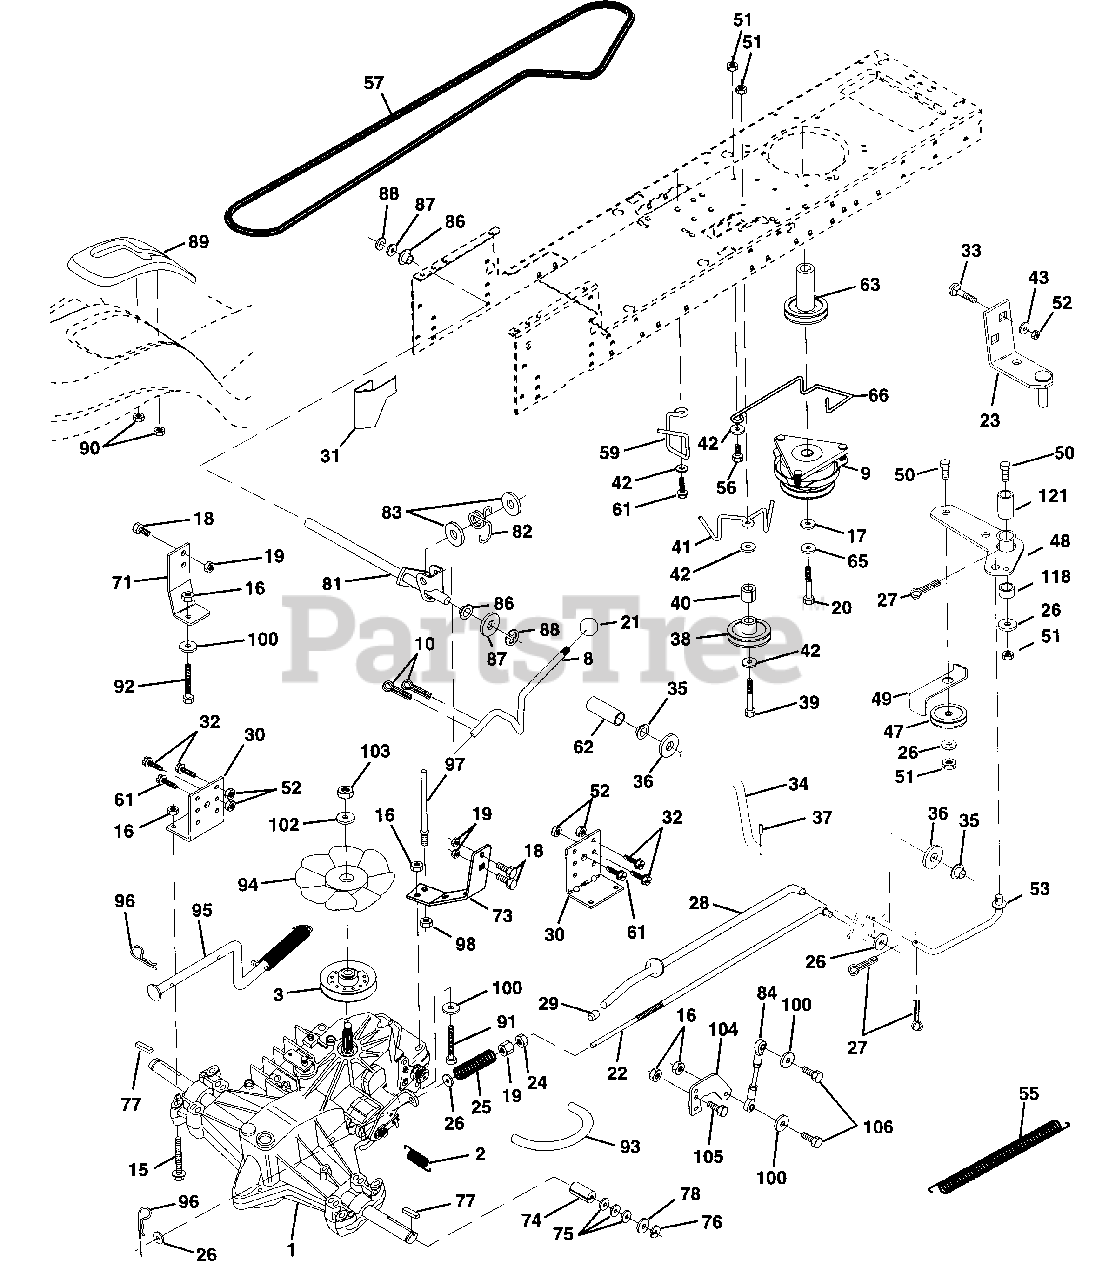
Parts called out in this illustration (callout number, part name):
1	Transaxle w/cas Hydro 310-0650
2	Spring, Return, Brake
3	Pulley, Transaxle Hydro 750 LT
8	Rod Shift STLT
9	Clutch Electric
10	Pin Cotter 1/8 x 1 CAD
15	Bolt Hex 5/16-18 Unc Flghd
16	Nut Lock Hex W/Ins. 5/16-18 Unc P
17	Washer 1-1/2 OD x 15/32 ID x .250
18	Bolt Fin Hex 3/8-16 Unc x 1 Gr.5
19	Nut Lock Hex W/Ins 3/8-16 Unc
20	Bolt, Hex 7/16-20 x 4-1/4 Ga. 5
21	Knob Deluxe 1/2-13 UNC BLK/BLK
22	Rod, Brake Hydro
23	Bracket Asm Mtg CL
24	Nut Hex Jam 3/8-16 UNC
25	Spring, Brake Rod
26	Washer
27	Pin Cotter 1/8 x 3/4 CAD.
28	Rod, Parking Brake
29	Cap,Parking Brake
30	Bracket, Transaxle
31	Keeper Belt Lh
32	Bolt Hex Hd 5/16-18 Unc x 3/4
33	Bolt Carriage 5/16-18 UNC x 3/4
34	Shaft, Foot Pedal
35	Bearing, Nylon
37	Pin, Roll
38	Pulley, Idler, Flat
40	Spacer Split
41	Keeper, Belt Idler
42	Washer 13/32 x 13/16 x 12 Ga
43	Washer 11/32 x 5/8 x 12 Ga.
47	Pulley, Idler, V-Groove Plastic
48	Bellcrank Assembly
49	Retainer, Belt Style Spring
50	Bolt
52	Nut Crown Lock 5/16-18
53	Link, Clutch
55	Spring, Return, Clutch
56	Bolt, Fin Hex 3/8-16 UNC x 1 1/4
57	V-Belt, Ground Drive
59	Keeper, Center Span
61	Screw Thdrol. 3/8-16 x 3/4 Ty. TT
62	Cover, Pedal Premium
63	Pulley, Engine
65	Washer Lock Hvy HLCL Spr 7/16
66	Keeper Belt Engine
71	Strap Torque Lh Hydro 18/20" T
73	Strap Torque Rh Hydro 0650
74	Spacer, Split
75	Washer 25/32 x 1-1/4 x 16 Ga.
77	Key, Square
78	Washer 25/32 x 1-5/8 x 16 Ga
81	Shaft Asm. Cross Hydro 20" Tires
82	Spring Torsion T/A
83	Washer 17/32 x 3/4 x 16 Ga.
84	Rod, Tie Hydro 20" Tires SPH Ball 4.75
86	Bushing Rod Stng. 629/632 ID
87	Washer 21/32 x 1-1/4 x 16 Ga.
88	Ring Klip #5304-62
89	Console, Hydro YT/GT Fender
90	Nut Self-Thd Wsh-Hd 1/4 Zinc
91	Bolt Fin Hex 5/16-18 x 2-1/4
92	Bolt Fin Hex 5/16-18 Unc x 1-1/2
93	Line Fuel Hydro 4"
94	Fan, Hydro 7"
95	Control Asm. Bypass Hydro
96	Retainer Spring 1" Zinc/Cad
97	Keeper Belt Rh Hydro 0750.18/20"
98	Nut Keps Hex 3/8-16 Unc
100	Washer 11/32 x 3/4 x 16 Ga.
102	Washer Belleville .501D x 1.50D
103	Nut Hex Jam Toplock 1/4-20 Unf
104	Arm, Control Hydro
105	Screw Cap Hex 5/16 x 18 x 1
106	Bolt Fin Hex 5/16-18 Unc x 1-1/4
118	Spacer Bellcrank
121	Nyliner Clutching STL
